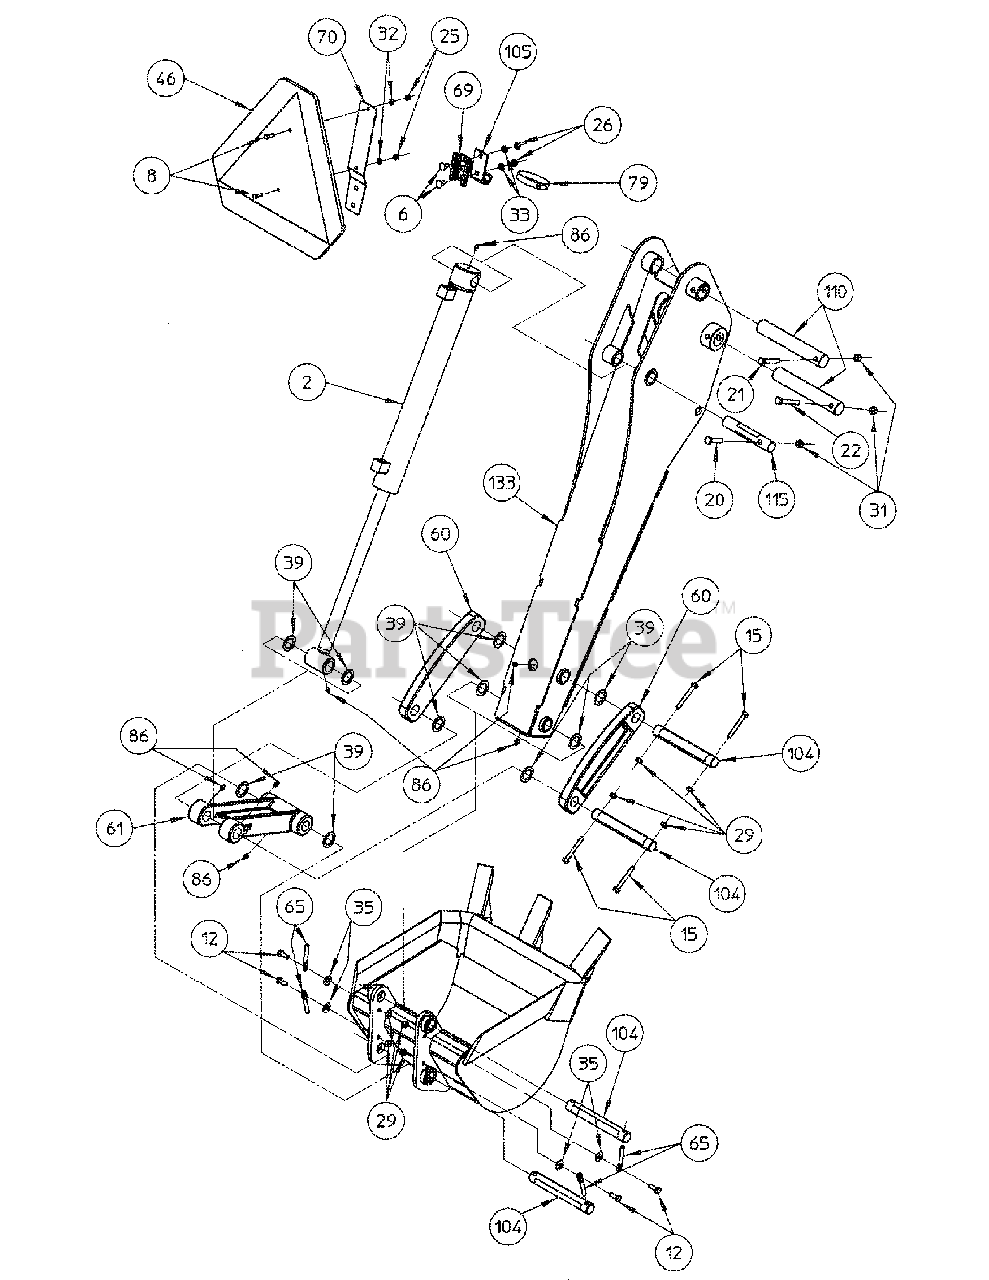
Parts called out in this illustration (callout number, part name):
1	Hydraulic Cylinder - Swing
2	Hydraulic Cylinder - Bucket
3	Hydraulic Cylinder - Stabilizer
4	Hydraulic Cylinder - Boom
5	Hydraulic Cylinder - Dipper
6	Bolt, Carriage 5/16 NC x 3/4"
7	Bolt, Carriage 5/16 NC x 1-1/4"
8	Bolt, 1/4 NC x 3/4"
9	Bolt, 5/16 NC x 3/4"
10	Bolt, 5/16 NC x 3/4" Thread Forming
11	Bolt, 5/16 NF x 3/4"
12	Bolt, 5/16 NF x 7/8"
13	Bolt, 5/16 NF x 1" Gr. 5
14	Bolt, 5/16 NF x 2-1/4" Gr. 5
15	Bolt, 5/16 NF x 2-1/2" Gr.5
16	Bolt, 5/16 NF x 4" Gr. 8
17	Bolt, 3/8 NF x 3/4"
18	Bolt, 3/8 NF x 1"
19	Bolt, 3/8 NF x 1-1/4"
20	Bolt, 3/8 NF x 1-3/4"
21	Bolt, 3/8 NF x 2-1/4"
22	Bolt, 3/8 NF x 2-3/4"
23	Bolt, 3/8 NC x 5-1/2" Long Gr.5
24	Bolt, 1/2 NF x 7/8"
25	Nut, 1/4 NC
26	Nut, 5/16NC
27	Locknut, 5/16 NC
28	Nut, 5/16 NF
29	Locknut, 5/16 NF
30	Lock Nut, 3/8NC
31	Locknut, 3/8 NF
32	Lockwasher, 1/4
33	Lockwasher, 5/16
34	Flat Washer. 5/16 STD
35	Washer, 5/16 SAE
36	Flat Washer, 3/8 SAE
37	Flat Washer, 1/2" Hardened
38	Machine Bushing, 1-1/4 OD x 3/4 ID x 14Ga.
39	Machine Bushing 1-1/2" OD x 1" ID x 18Ga.
40	Machine Bushing 1-7/8" OD x 1-1/4" ID x 18Ga.
41	Machine Bushing, 2-1/2 OD x 1-3/4ID x 18Ga
42	Cotter Pin, 3/32" Dia x 3/4"
43	Cotter Pin, 3/16 x 1-1/4"
44	Cotter Pin, 1/4 x 1-1/2"
45	Hair Pin Cotter, 3/64" Dia x 11/16"
47	Adapter Union, 9/16-18M x 3/8NPTF
48	Hydraulic Tee
49	Adapter Union, 3/4-16M x 3/8NPTF x Straight
50	Adapter Union, 3/8NPTM x 3/8NPTF x 90 degree
51	Adapter Union, 9/16-18M x 3/8NPTF x 90 degree
52	Adapter Union, 7/8-14M x 3/8 NPTF x 90 degree
53	Adapter Union, 3/4-16M x 3/8NPTF x 90 degree
54	Coupler Body 3/4-16F Thread
55	Coupler Nose 3/4-16F Thread
56	Garlock Bearing, 028DXR020
57	Bronze Bearing
58	Garlock Bearing, 028DXR016
59	Stabilizer Pad Weldment
60	Guide Link
61	Bucket Link
62	Street Pad
63	Clevis Pin, 3/16" Dia x 5/8"
64	Clevis Pin, 1/4" Dia x 7/8"
65	Pin Retainer
66	Pin Retainer
67	Boom Lock Pin
68	Swing Lock Pin
69	SMV Socket
70	SMV Bracket
72	Ball Joint - Shouldered
73	Ball Joint
74	Control Knob
75	Rubber Cap
76	Plastic Tie T150L
77	Plastic Tie T120 L
78	Plastic Tie T50L
80	Hose Sleeve FC425-16 X 30" Long
81	Hose Sleeve FC425-16 X 19" Long
82	Hose Sleeve FC425-16 X 48" Long
83	Hose Sleeve FC425-16 X 63" Long
84	Hose Sleeve FC425-16 X 79" Long
85	Grease Fitting
86	Grease Fitting (Two are part of #000187 Cyl.)
87	Grease Fitting (Two are part of #000187 Cyl.)
88	Hydraulic Hose, 3/8NPTM x 3/8NPTM x 20" long
89	Hydraulic Hose, 3/8NPTM x 3/8NPTM x 23" long
90	Hydraulic Hose, 3/8NPTM x 3/8NPTM x 30" long
91	Hydraulic Hose, 3/8NPTM x 3/8NPTM x 58" long
92	Hydraulic Hose, 3/8NPTM x 3/8NPTM x 76" long
93	Hydraulic Hose, 3/8NPTM x 3/8NPTM x 92" long
94	Hydraulic Hose, 3/8NPTM x 3/8NPTM x 110" long
95	Hyd. Hose, 3/8ID 3/8NPTF M x 3/4-16 Str O x 49"
96	Hyd. Hose, 3/8ID 3/8NPTF M x 3/4-16 Str O x 34"
97	Control Valve
98	Adapter Union, 7/16-20M x 3/8NPTF
99	Rear Shroud
100	Stabilizer Lever Control Rods
101	Control Rod
102	Pivot Pin, Boom Cyl. Rod 1-1/4" Dia. x 6" Long
103	Thrust Washer
104	Pivot Pin, Bucket 1"Dia. x 7-3/8" Long
105	SMV Socket Mount
106	Stabilizer Control Lever
107	Lever Bracket
108	Hose Clamp - Short
109	Pivot Pin, 3/4" Diameter x 4-1/16" Long
110	Pivot Pin, Dipperstick 1-1/4" Dia. x 7-15/16" Long
111	Pivot Pin, Stabilizer Leg
112	Pivot Pin Weldment
113	Pivot Pin, Stabilizer Pad 3/4" Dia. x 4-15/16" Long
114	Pivot Pin, Stabilizer Cyl. Rod
115	Pivot Pin, Bucket Cyl. Base 1" Dia. x 5-7/8" Long
116	Pivot Pin, Boom Cyl. Base 1-1/4" Dia. x 7-1/4" Long
117	Lower Pivot Pin Weldment
118	Seat Plate Weldment
119	RH Pivot Weldment
120	LH Pivot Weldment
122	Stabilizer Leg Weldment
123	Upper Pivot Pin Weldment
124	Pivot Pin Weldment, Boom 1-3/4" Dia. X 2-3/4" Lg
125	RH Toe Shield
126	LH Toe Shield
127	Hose Clamp - Long
128	Grab Bar Weldment
129	Mainframe Weldment
130	Valve Mount Weldment
131	Swing Frame Weldment
132	Front Shroud Weldment with Decals
133	Dipperstick Weldment
134	Boom Weldment
135	Right Hand Joystick Weldment
136	Left Hand Joystick Weldment
